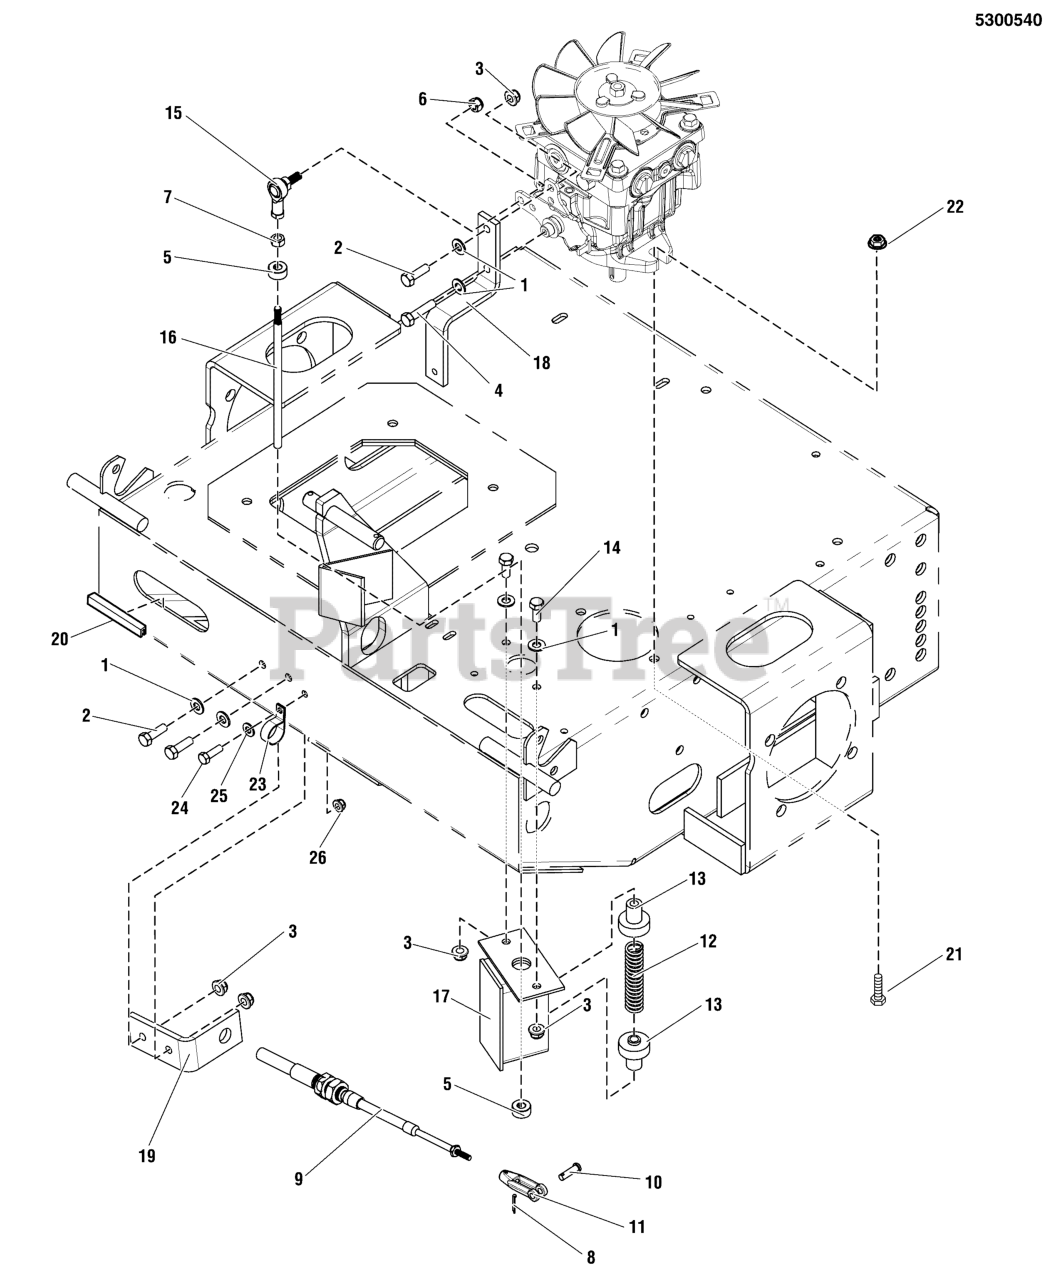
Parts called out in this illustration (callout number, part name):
1	WASHER, 5/16" SAE
2	BOLT, 5/16-18 X 1" GD5 YZ
3	NUT, 5/16-18 HEX NYLOCK FLANGE
4	BOLT, M8-1.25 X 25MM GR 8.8
5	COLLAR, 5/16" SET
6	NUT, 5/16-24 HEX NYLON LOCK
7	NUT, 5/16-24 HEX
8	PIN, 3/32 X 0.750, COT, ZINC/CLEAR
9	CABLE, SPEED CONTROL, 36"
10	PIN, CLEVIS, 1/4 X 7/8, PLATED
12	SPRING, BRAKE RETURN
13	SPRING RETURN GUIDE
14	BOLT, 5/16-18 X 1" GD5 YZ
15	BALL JOINT, 5/16-24 RH FEMALE W/STUD, BR
16	ROD, NEUTRAL RETURN
17	WELD, NEUTRAL RETURN, TWR - RED
18	BAR, 1/4 X 1.00, MOTION CONTROL - RED
19	BRACKET, CABLE MOUNT - RED
20	BLACK SOFTONE Q-TRIM 3.5" LONG
21	BOLT, 3/8-16 X 1-1/4" GD5 CZ
22	NUT, 3/8-16 HEX SERRATED FLANGE
23	CLAMP, VINYL
24	BOLT, 1/4-20 X 3/4" GD5 YZ
25	WASHER, 1/4 SAE
26	NUT, 1/4-20 NYLON FLANGE
